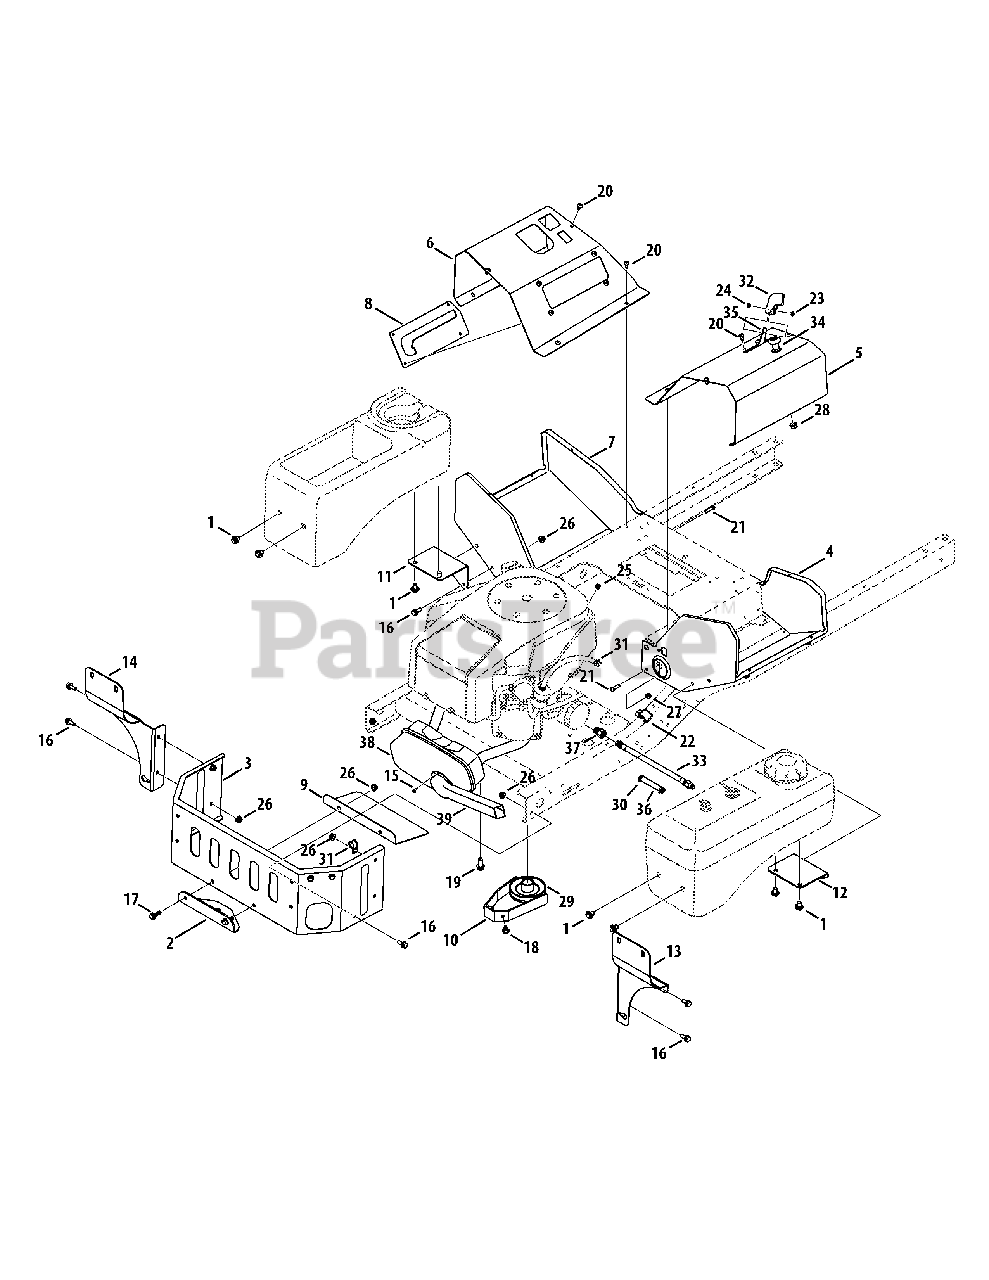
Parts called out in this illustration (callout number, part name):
1	Hex Screw, M10-1.5 x .500 x 8.8
2	Hitch Bracket
3	Bumper Bracket
4	RH Lower Console
5	RH Upper Console
6	LH Upper Console
7	LH Lower Console
8	Parking Brake Lock Bracket
9	Muffler Mount Bracket
10	Belt Keeper Bracket
11	Left Tank Support Bracket
12	Right Tank Support Bracket
13	Tank Support Bracket RH
14	Tank Support Bracket LH
15	Hex Washer Screw, #8-18 x 0.500
16	Hex Flange Screw, 5/16-18
17	Hex Flange, 5/16-18 x 1.0
18	Hex Washer Screw, 5/16-18 x .750
19	Tap Screw, 3/8-16 x 1.25
20	Screw, 1/4-20 x .5
21	Screw, 1/4-20 x 1.0
22	Clamp, 1.0
23	Machine Screw, #8-32 x0.375
24	Hex Nut, #8-32
25	Sems Nut, 1/4-20
26	Flange Lock Nut, 5/16-18
27	Flange Lock Nut, 1/4-20
28	Flange Lock Nut, 3/8-16
29	Electric PTO Engine Pulley
30	Hose Clamp, .490
31	Clamp, 9/16
32	Throttle Knob
33	Oil Drain Extension Hose
34	Choke Cable
35	Throttle Cable, 39.0 x .62
36	Fuel Hose, 1/4
38	Kohler Twin Muffler
39	Long Muffler Deflector
